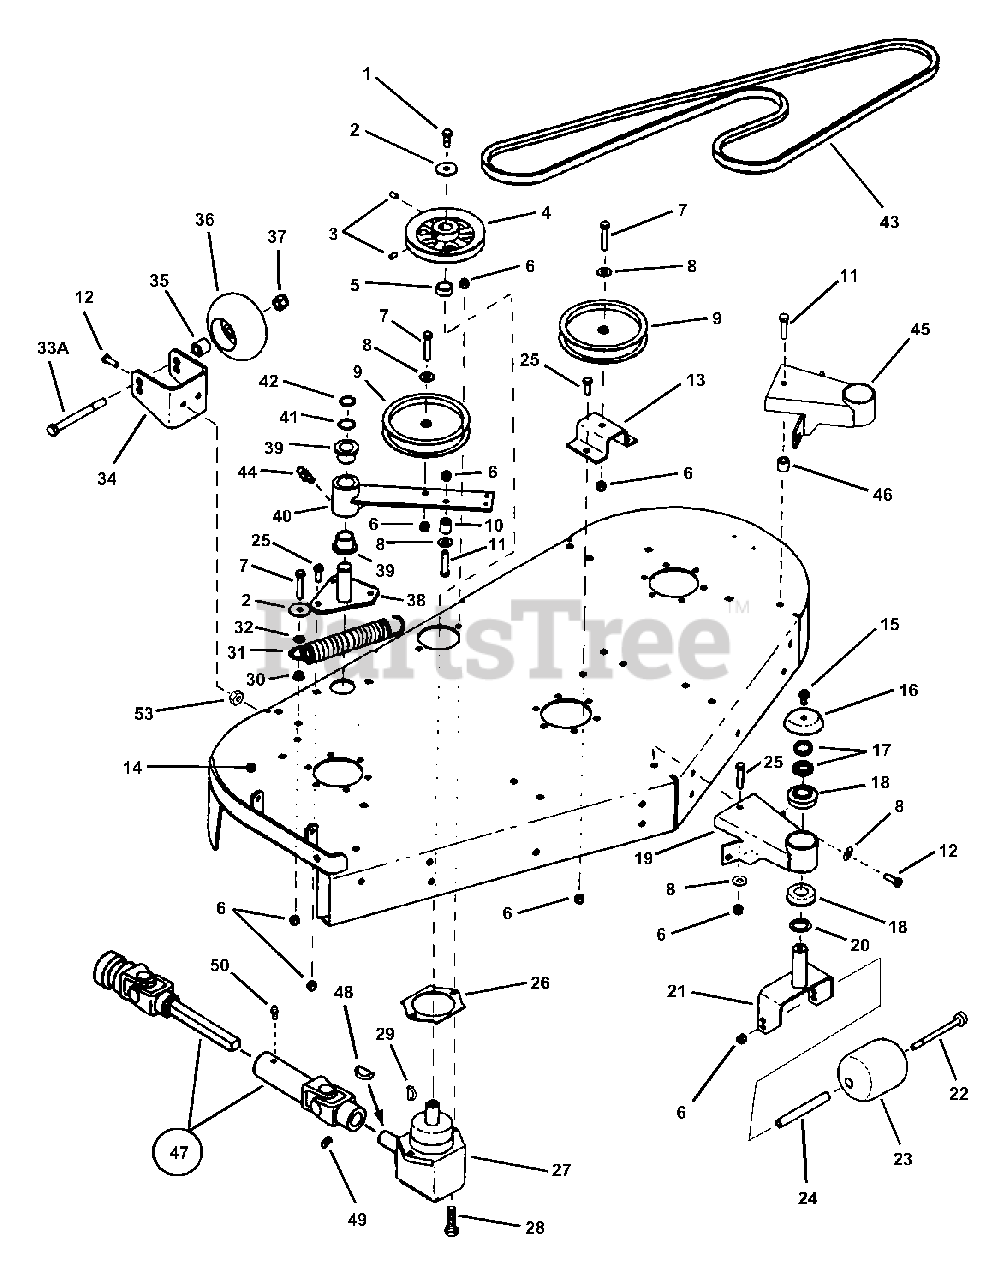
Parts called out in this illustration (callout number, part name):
1	BOLT, 3/8-24 X 1" GD8 YZ
2	WASHER, 13/32" Flat
3	SET-SCREW, 5/16" x 5/8" Socket Head
4	PULLEY, 5.25 Cast
5	SPACER
6	NUT, 3/8-16 HEX NYLON LOCK
7	BOLT, 3/8-16 X 2, GD5, CZ
8	WASHER, 3/8" USS
9	PULLEY, 5-1/2 Idler
10	SPACER, 3/4" Outside Diameter
11	SCREW, 3/8-16 x 1-3/4" Hex Head Cap Gr. 5
12	BOLT, 3/8-16 X 1" GD5 CZ
13	STAND, Fixed Idler
14	WELDMENT, Deck, 61"
15	SCREW, 5/16-18 x 3/4" Hex Self Tapping
16	CAP, Caster Shaft
17	SPACER, 1" x 1 3/8 x .30" (PM)
18	BEARING, Radial
19	WELDMENT, Gauge Wheel Bracket
20	BUSHING, 1" Machine
21	WELDMENT, Gauge Wheel Caster
22	BOLT, 3/8-16 X 6" GD5 CZ
23	ROLLER, 3-3/4" x 4-13/16" Nylon
24	TUBE, Axle
25	BOLT, 3/8-16 x 1" Carriage, Grade 5
26	GEARBOX, Shim
27	GEARBOX, Right Angle (Peerless Series 1000-52)
28	BOLT, 3/8-16 X 1-1/4" GD5 CZ
29	KEY, #6 x 5/8" Woodruff
30	NUT, 3/8-16 HEX SERRATED FLANGE
31	SPRING, Extension
32	RETAINER, 3/8" Bolt
33A	BOLT, 1/2-13 X 5 GD5 YZ
34	FORK, Gauge Wheel
35	SPACER, Gauge Wheel
36	WHEEL, Gauge
37	NUT, 1/2-13 Hex Nylock
38	WELDMENT, Idler Pivot
39	BUSHING, Caster
40	WELDMENT, Idler Arm
41	WASHER, 1-1/32" Flat
42	RING, 1" External Retaining
43	BELT, 61" HB (134-1/2")
44	ZERK, 1/4-28 Self Tapping
45	WELDMENT, Gauge Wheel
46	SPACER, 3/8" Inside Diameter
47	DRIVESHAFT, Telescoping
48	KEY, #9 Woodruff
49	SET SCREW, 3/8-16 x 3/8" Hex Recess
50	FITTING, 1/4-28 Lube
53	NUT, 3/8-16 Hex Center Lock
